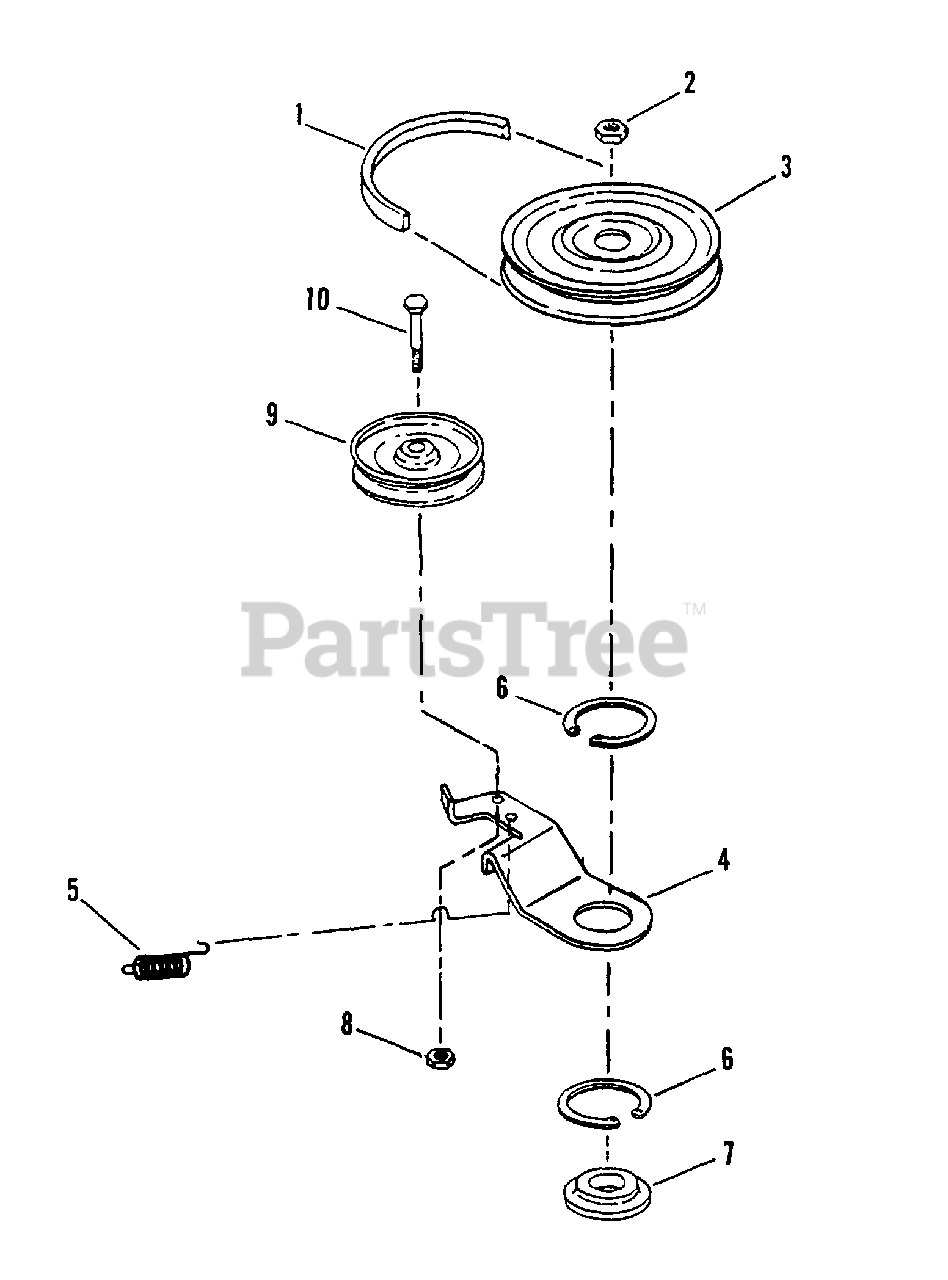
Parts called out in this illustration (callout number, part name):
1	BELT, Drive
2	NUT, 3/4-16 Hex Jam
3	PULLEY, Drive
4	ARM, Brake
5	SPRING, Idler
6	RING, 2" External Retaining
7	WASHER, Spindle
8	NUT, 3/8-16 Hex Center Lock, Grade 5 or B
9	PULLEY, Idler
10	SCREW, 3/8-16 x 2" Hex Head Cap, Grade 5
